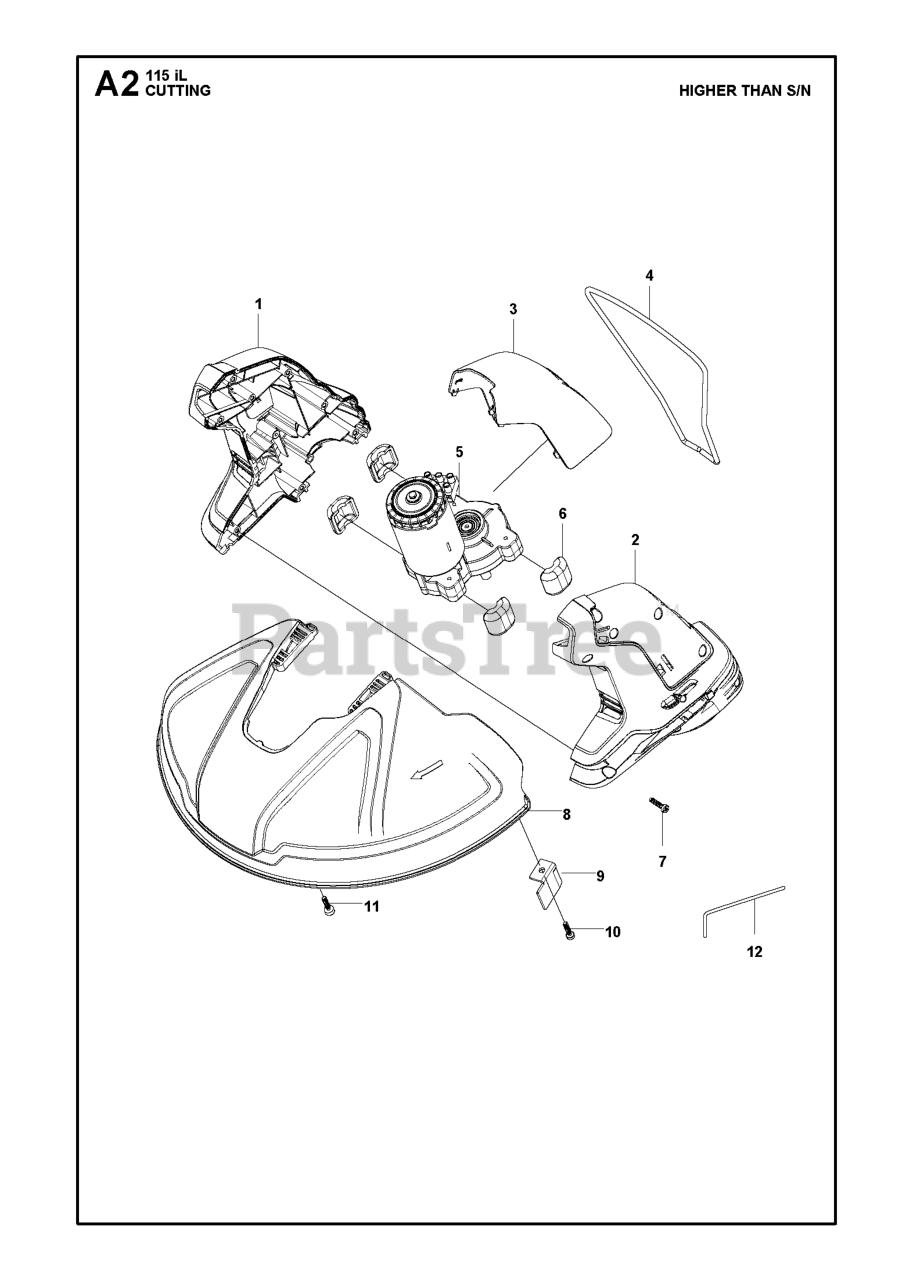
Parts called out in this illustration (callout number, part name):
1	HOUSING MOTOR HOUSING L 36V
2	HOUSING MOTOR HOUSING R 36V
3	COVER MOTOR HOUSING
4	RING PLANT GUARD
5	GEARBOX ASSY 115IL TRIMMER
7	SCREW ST4X16
8	GUARD FOR CUTTING HEAD
9	BLADE 330MM
10	SCREW ST4X16
11	SCREW ST4*16
